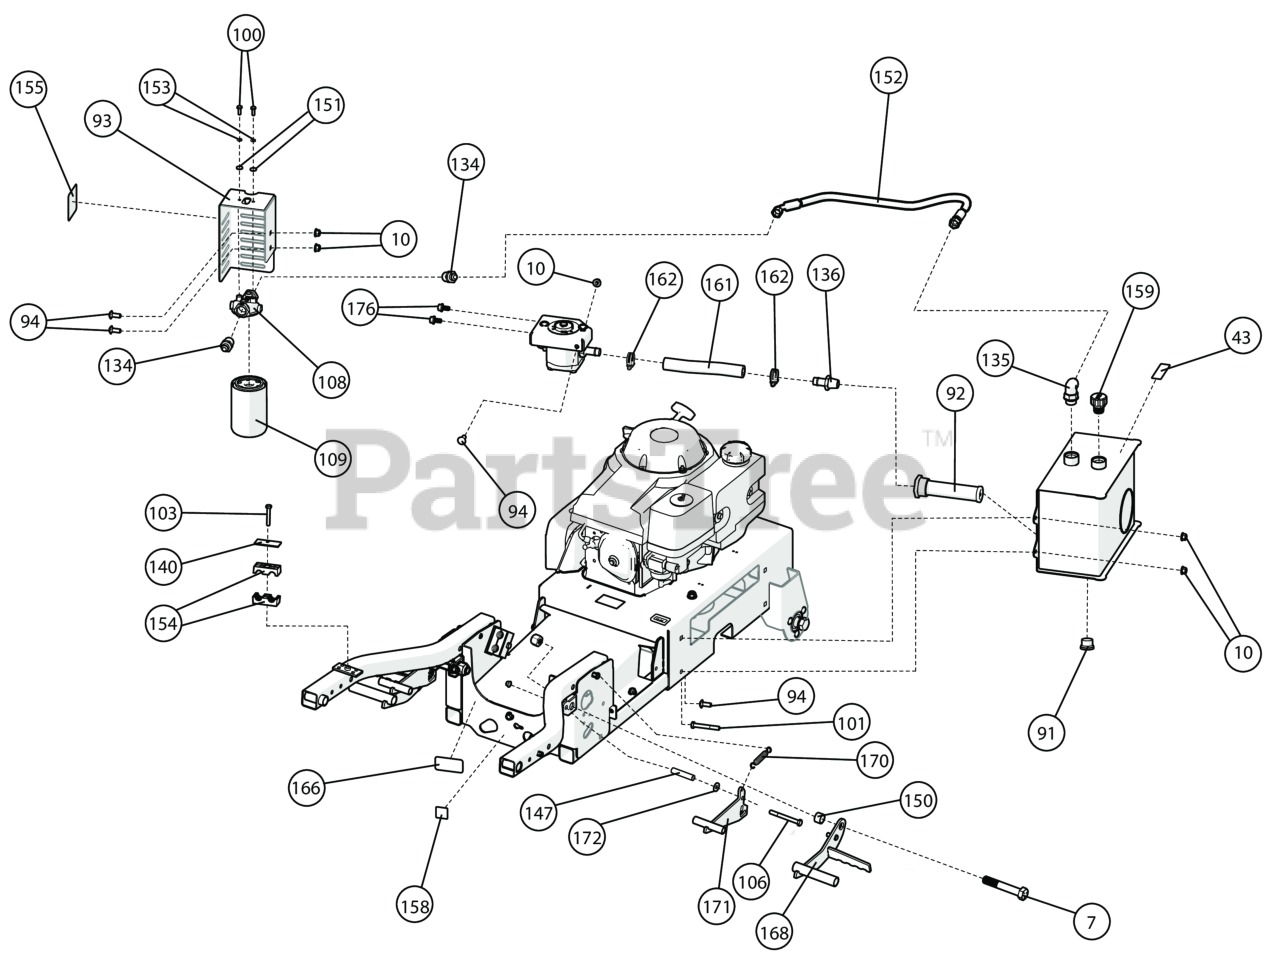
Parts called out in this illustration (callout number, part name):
7	SCR-CAP, HEX, 3/4-10 X 4.500" ZP
10	NUT-HEX-NYLK, FLG .375"-16 ZP
43	LABEL HOT SURFACE
91	PLUG, HYDRAULIC O-RING SAE 6
92	STRAINER, 100 MESH
93	WA, FILTER MOUNT
94	BOLT CARRAIGE 3/8-16 X 1" ZP
100	SCREWCAP 1/4"-20X3/4" HCS ZP
101	SCREWCAP 3/8"-16X2 3/4" ZP
103	SCREWCAP 5/16"-18X2" HCS ZP
106	SCREWCAP 3/8" - 16 X 3 1/2 HCS
108	ZAF-07 SPIN ON FILTER HEAD MOUNT
109	SPIN ON FILTER, AE-25
134	ADAPTER, HYDRAULIC, 3/4 NPT TO 1/2 JIC
135	ADAPTER, HYD, 90DEG, SAE-12 TO 1/2 JIC
136	ADAPTER, HYD., 1.0 NPT TO 3/4 BEADED
140	PLATE CLAMP COVER
147	SPCR, PEDAL MOUNT BRKT
150	SPACER SEED BOX AXLE
151	WASHER 1/4"SAE9/32"X5/8"X1/16"
152	FILTER TO TANK HOSE ASSY 29.5" OAL
153	WASHER LOCK 1/4" S/T MED
154	INSERT, WELD ON CLAMP, .50"
155	LABEL WARNING HIGH PRESSURE
158	LABEL TIE DOWN
159	CAP, HYDRAULIC, 3/4 NPT W/ SPLASH GUARD
161	HOSE, HYDRAULIC, .75" ID X 8.50" LG.
162	CLAMP, HOSE, WORM GEAR, 11/16" TO 1-1/4"
166	DECAL, TRANSAXLE BYPASS
168	WA, BRAKE PEDAL, RIGHT
170	SPRING, EXT 4.090" X Ø.701 X 14LBF/IN
171	WA, PEDAL RELEASE
172	WSHR-NYL, FLT, .385" X .880" X .125"
176	SER HEX WASHER 3/8" - 16
